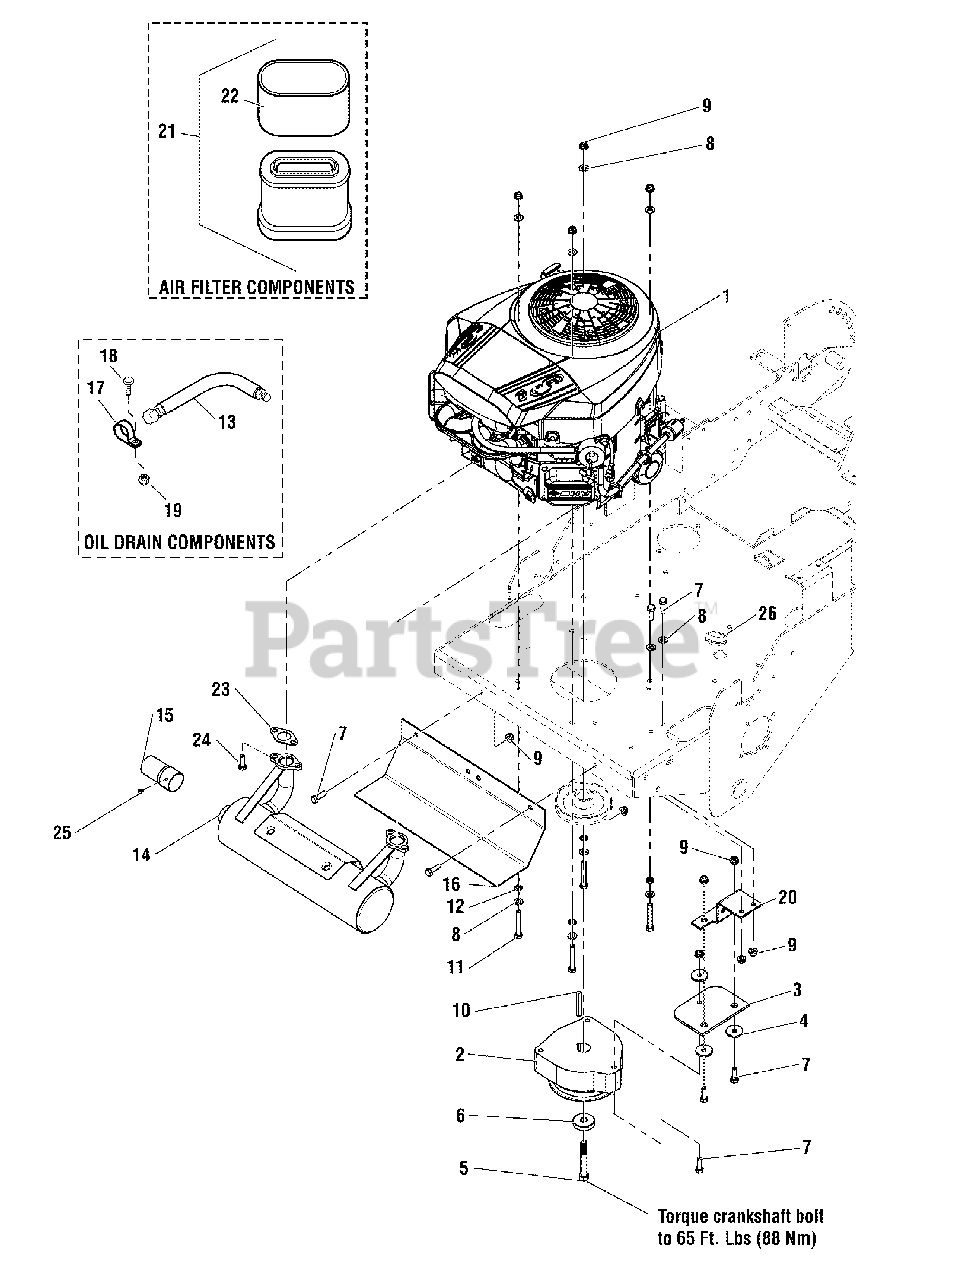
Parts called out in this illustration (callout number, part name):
1	* ENGINE-24HP B&S, ELS #44M777-0113-E1
2	CLUTCH, ELECTRIC, 1" SHAFT
3	CLUTCH ANCHOR PAD
4	WASHER, .34 X 1.25 X 10GA
5	BOLT, CRANKSHAFT, 7/16-20 X 3-1/4" YZ
6	SPACER, .45 X 1.62 X .37
7	BOLT, 5/16-18 X 1" GD5
8	WASHER, 5/16" SAE
9	NUT, 5/16-18 HEX NYLOCK FLANGE
10	KEY, 1/4" SQ. X 3-1/2"
11	BOLT, 5/16-18 X 2-1/4" GD5
12	WASHER, 5/16" INT. TOOTH LOCK
13	HOSE, OIL DRAIN
14	MUFFLER, 22HP B&S - ELS - IS500Z
15	EXTENSION, TAILPIPE, 3" - BLK
16	PLATE, HEAT SHIELD
17	CLAMP, VINYL INSULATED
18	BOLT, 1/4-20 X 3/4" GD5
19	NUT, 1/4-20 HEX NYLOCK FLANGE
20	ANCHOR, CLUTCH
21	AIR CLEANER W / PRE CLEANER (SV)
22	PRE CLEANER (SV)
23	GASKET, EXHAUST
24	SCREW, SEM HEX HEAD
25	SCREW
26	GROMMET
